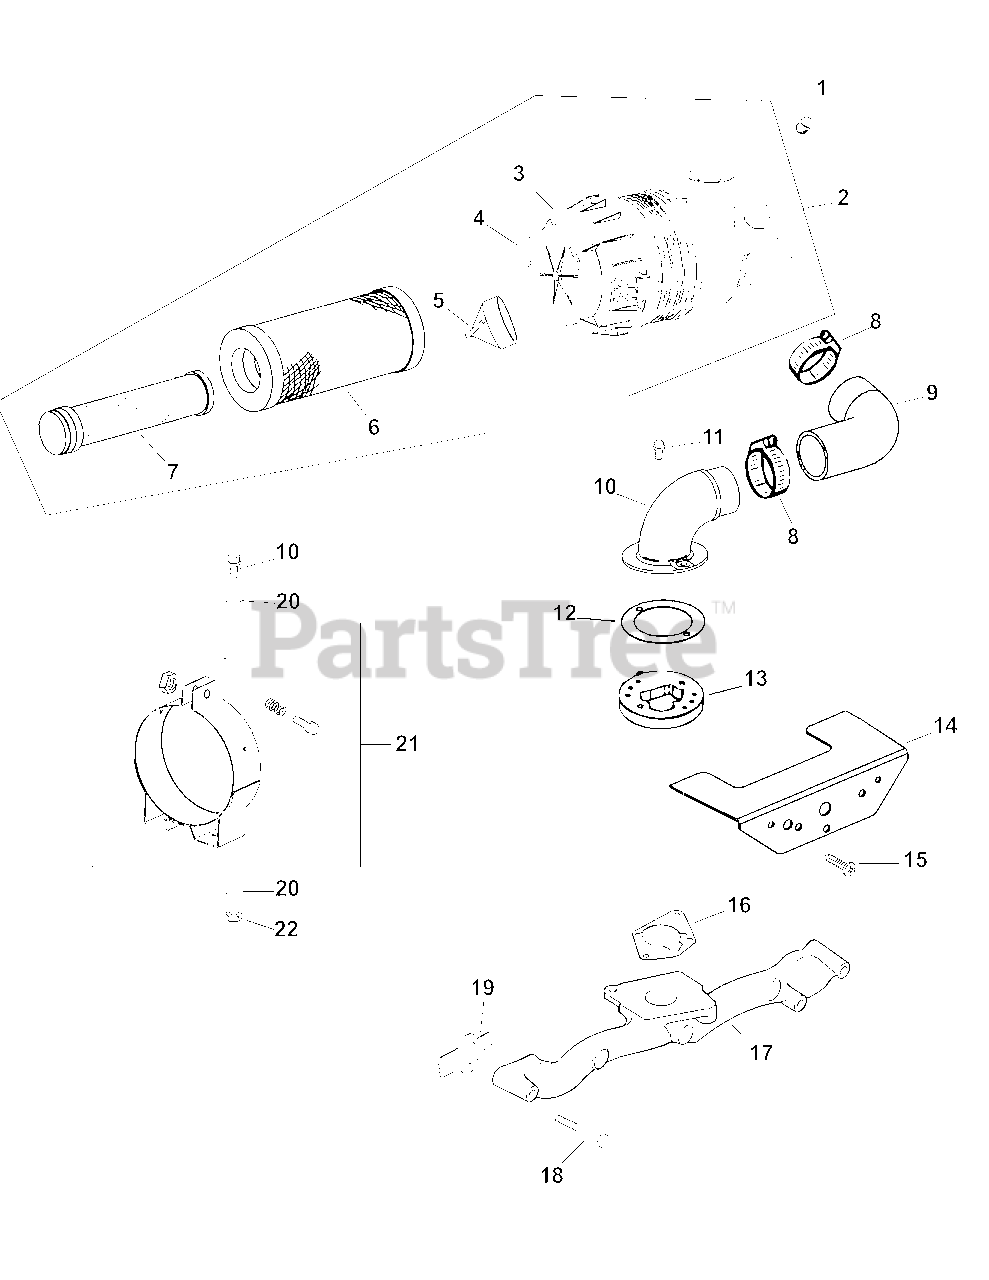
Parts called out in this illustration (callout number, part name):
2	Air cleaner assembly 5-1/4" (Includes 3-8)
3	Cover assembly, plastic air cleaner (Includes 4)
4	Clip
5	Valve, dust ejector
6	Element, air cleaner - primary
7	Element, safety
8	Clamp, hose (2)
9	Hose, air cleaner
10	Adapter, remote air cleaner
11	Screw, hex. flange M6x1.0x16 (6)
12	Gasket, adapter
13	Adapter assembly
14	Shield, debris
15	Screw, phillips hd. 11-16x3/4" (2)
16	Gasket, air cleaner base
17	Manifold, intake
18	Screw, hex. flange M6x1.0x55 (4)
19	Gasket, intake manifold (2)
20	Washer, plain (4)
21	Bracket, air cleaner
22	Nut, hex. lock (2)
